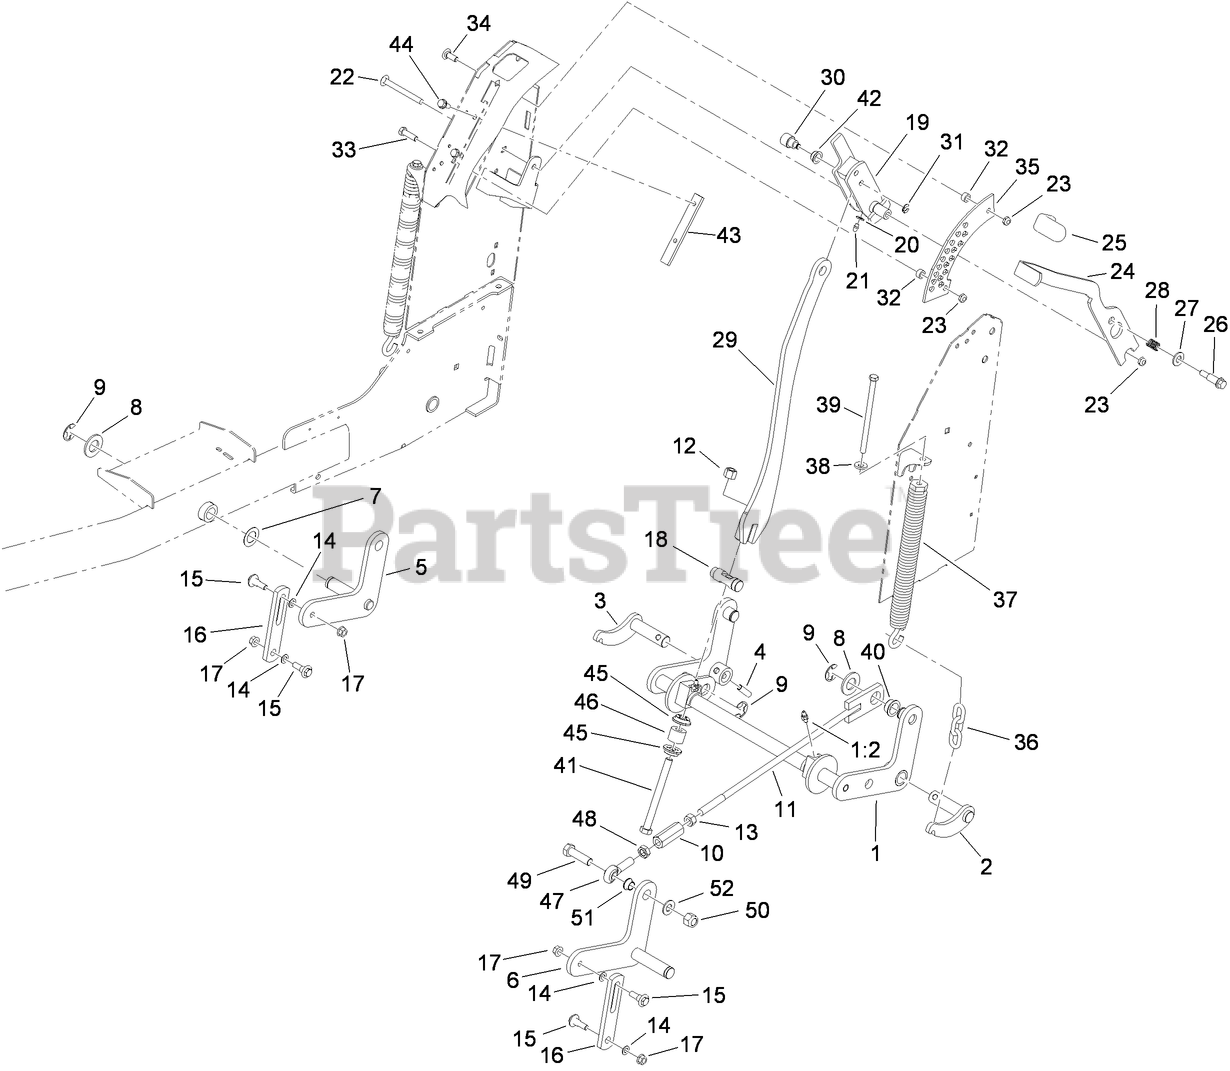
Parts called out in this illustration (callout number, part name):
1	REAR CROSSSHAFT ASM
1:2	FITTING-LUBE, 45 DEG
2	SHAFT-PIVOT, LH
3	SHAFT-PIVOT, RH
4	PIN-SPIRAL
5	RH LIFT ASM
6	LH LIFT ASM
7	WASHER-THRUST
8	WASHER-FLAT
9	RING-RETAINING, EXT
10	LINK-LIFT
11	LIFT ROD ASM
12	NUT-LOCK, NI
13	NUT-HH
14	WASHER
15	SCREW-SHOULDER, HHF
16	LINK-LIFT
17	NUT-HF
18	PIN-HOC
19	HOC HANDLE ASM
20	WASHER-FLAT
21	FITTING-GREASE
22	SCREW-CARR
23	NUT-LOCK, NI
24	LEVER-HOC
25	GRIP-LEVER
26	SCREW-SHOULDER
27	WASHER-FLAT
28	SPRING
29	BAR-LIFT
30	HUB-PIVOT
31	RING-RETAINING
32	SPACER
33	SCREW-HH
34	SCREW-CARR
35	BRACKET-HOC
36	CHAIN-DECKLIFT
37	SPRING-EXTENSION
38	WASHER-BELLEVILLE
39	BOLT-TAP, HH
40	BEARING-FLANGE
41	SCREW-HH
42	BEARING-FLANGE
43	SKID-HANDLE, LIFT
44	SCREW-HWHTF
45	SEAT-SPRING
46	SPRING-URETHANE
47	BALLJOINT-SPHERICAL
48	NUT-JAM
49	SCREW-HH
50	NUT-LOCK, NI
51	BUSHING
52	WASHER-FLAT
